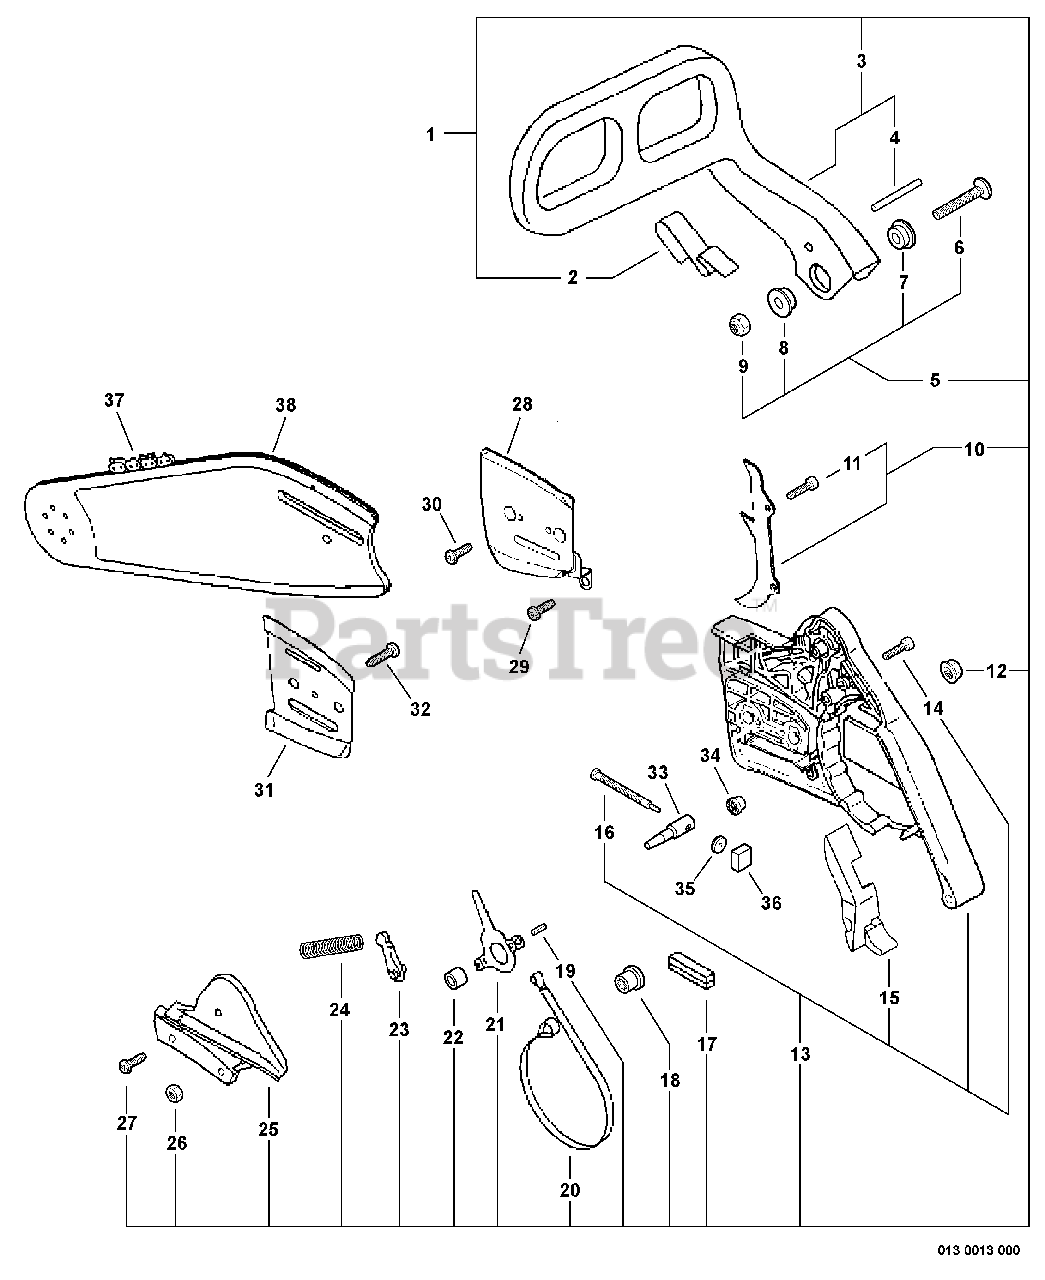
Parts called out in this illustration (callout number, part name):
1	BRAKE ASSY, CHAIN
2	SPRING, FLAT
3	LEVER, BRAKE
4	PIN 3.5×26
5	SCREW KIT
6	SCREW 5×35
7	COLLAR 5
8	COLLAR 5.3×10×13×L5
9	NUT, LOCK M5
10	SPIKE KIT, BUMPER
11	BOLT 5×12
12	NUT, FLANGE M8×1.25
13	GUARD KIT, SPROCKET
14	SCREW 3×18
15	CUSHION
16	SCREW, CHAIN TENSION
17	SEAL, BRAKE
18	ADJUSTER, BRAKE
19	PIN, SPRING 4×8.8
20	BAND, BRAKE
21	LEVER, BRAKE
22	SPACER 8×12×9
23	STOPPER, BRAKE
24	SPRING, BRAKE
25	COVER, BRAKE
26	NUT 3 MM
27	SCREW 4×12
28	PLATE, GUIDE - OUTER
29	SCREW 4×10
30	SCREW 3×6
31	PLATE, GUIDE - INNER
32	SCREW 4×8
33	TENSIONER, CHAIN
34	GEAR, BEVEL
35	GEAR, BEVEL
36	COLLAR - 8
37	CHAIN -- CARBICHAIN QUICKVENT
38	GUIDE BAR - QUICKVENT
